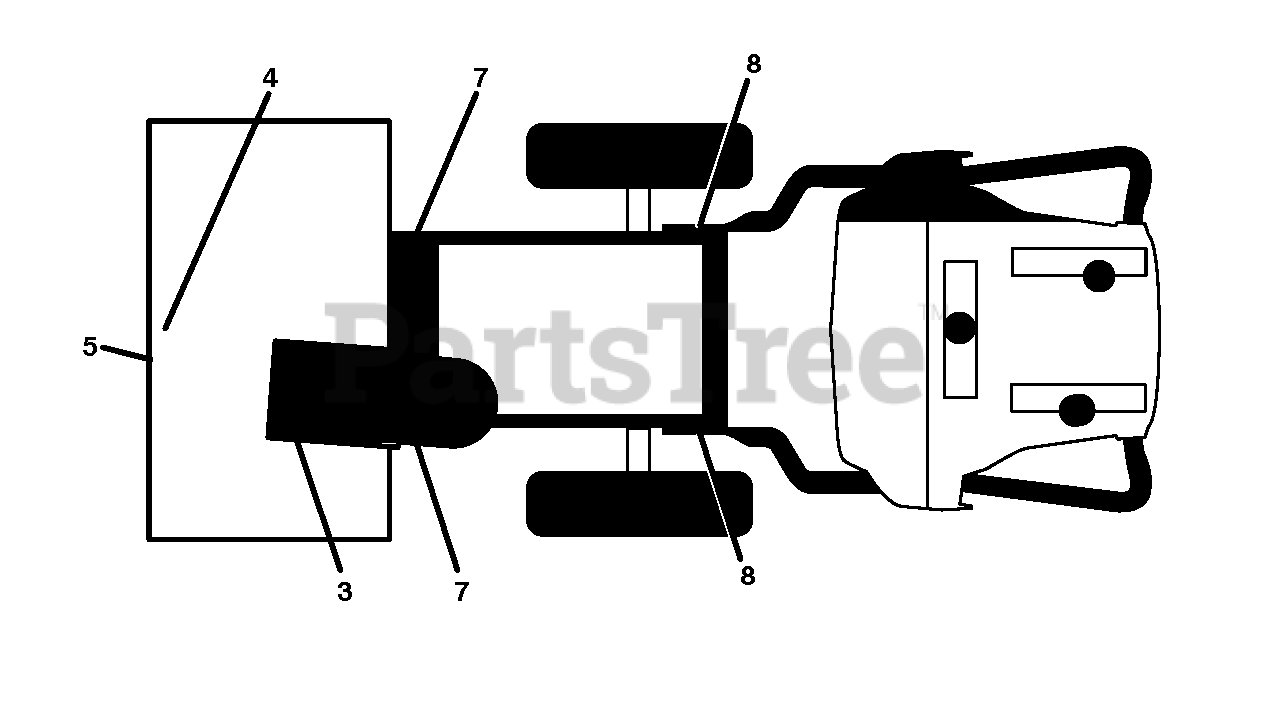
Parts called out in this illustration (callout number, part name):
3	DECAL.CHUTE.SAFETY.EU/SC.17
4	DECAL.AUGER."
5	DECAL.AUGER.POULAN PRO 27.254C
7	DECAL.BELT.GUARD.
8	DECAL.AUGER.SAFETY.
